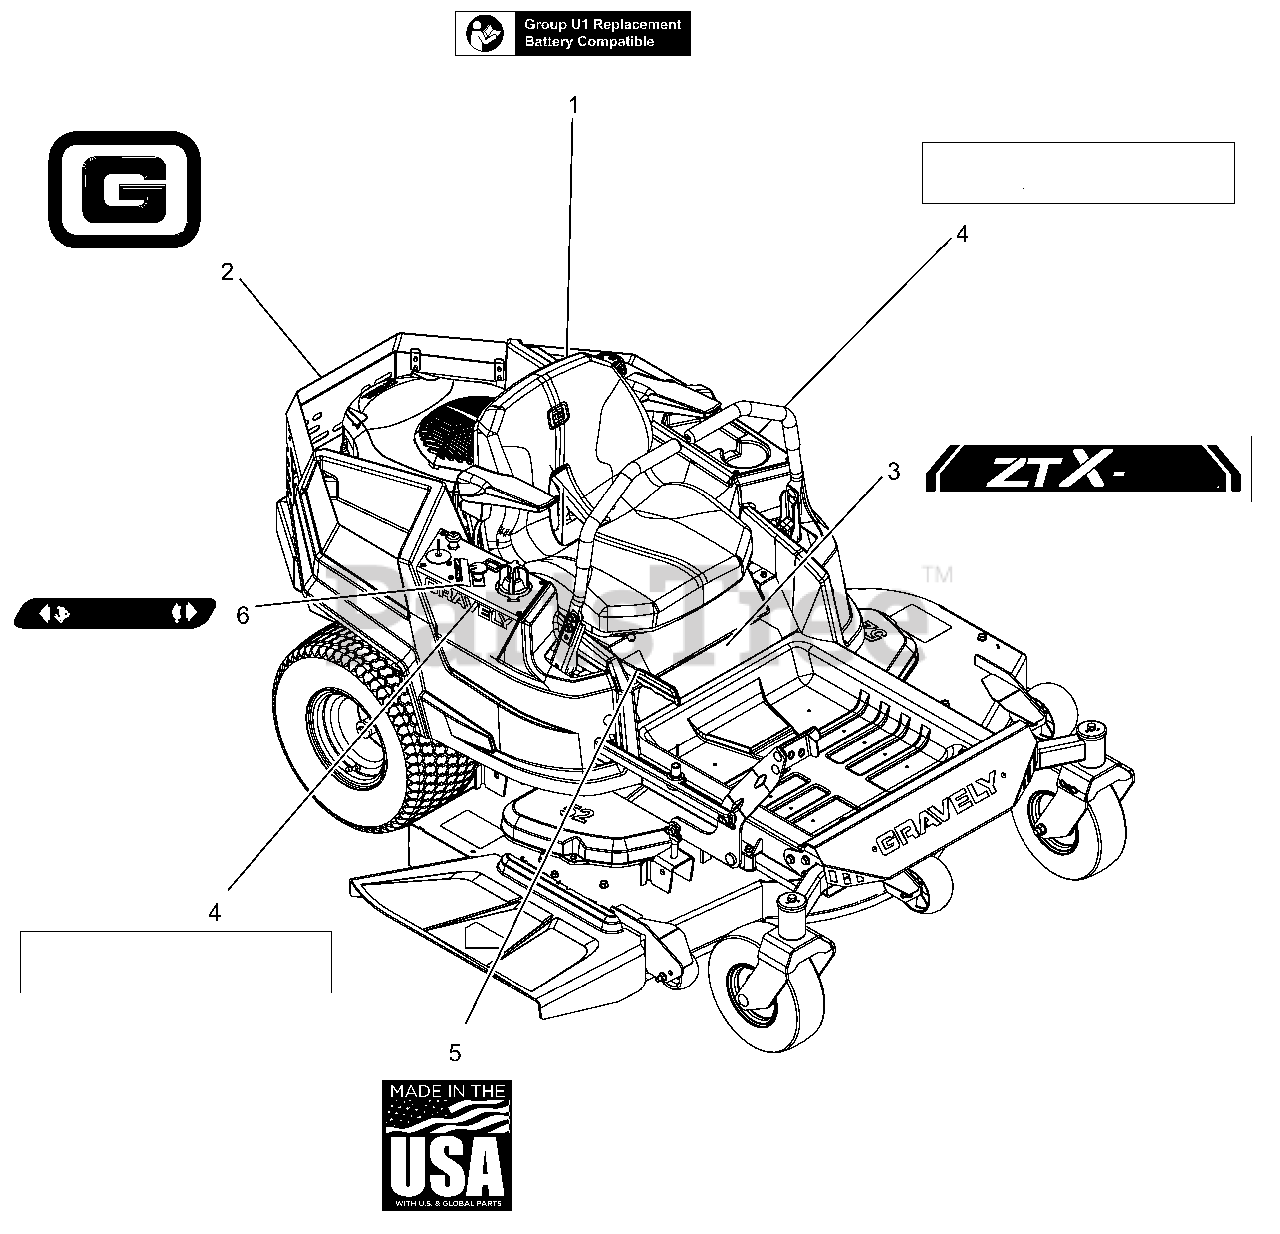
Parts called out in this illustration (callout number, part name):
1	DECAL, U1 BATTERY REPLACEMENT
2	DECAL, GRAVELY BRAND
3	DECAL, GRAVELY ZT X 52
4	DECAL, 9.5" GRAVELY LOGO
5	DECAL, MADE IN USA
6	DECAL, DASH DECAL
